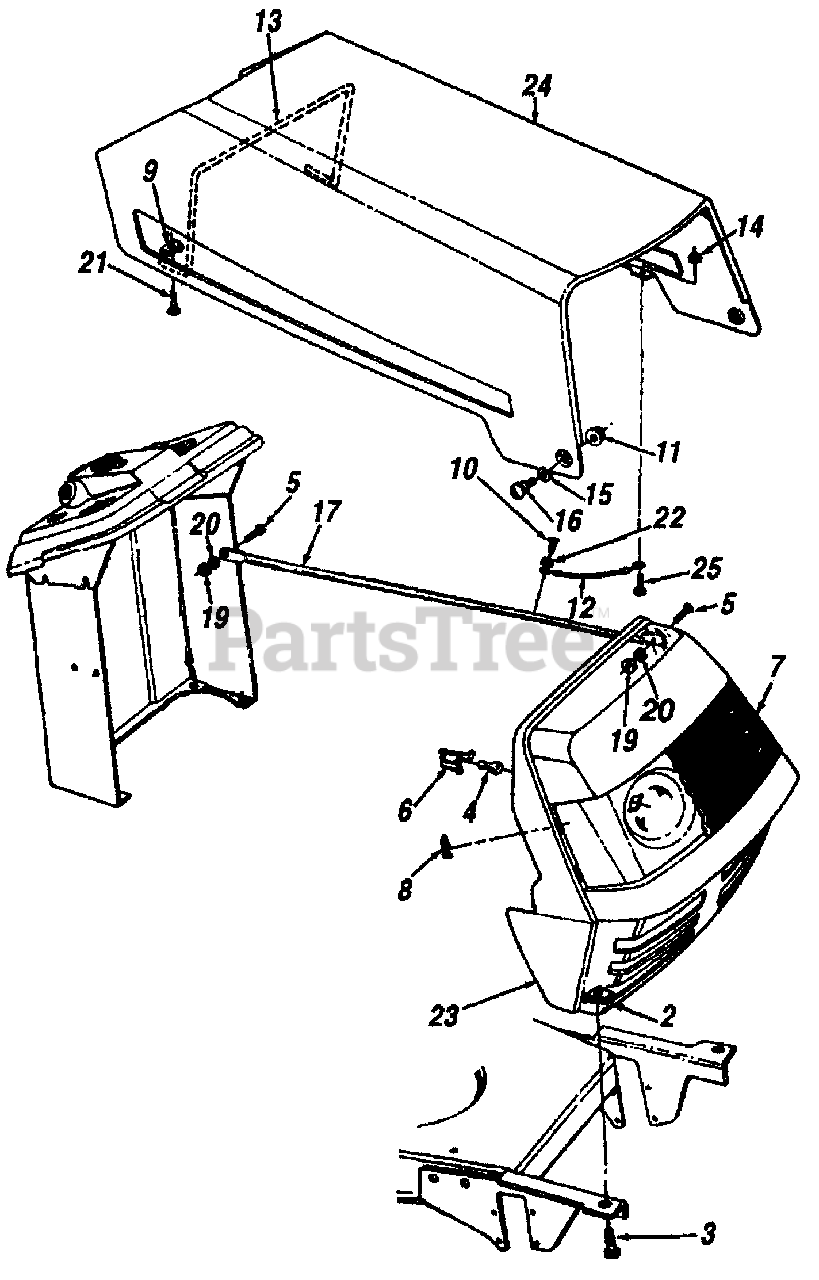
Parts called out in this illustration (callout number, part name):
2	U-Nut 5/16-18 Thd.
3	Hex Bolt 5/16-18 x .75" Lg.
4	Bulb
5	Hex Bolt 1/4-20 x .62" Lg.
6	Socket
7	Lens
8	Int. Cotter Pin 5/16" Dia.
9	Speed Nut
10	Truss Mach. B-Tap Scr. #10 x .5"
11	Lock Nut 1/4-20 Thd.
12	Hood Stop
13	Hood Spring
14	Hex Sems Nut #10-24 Thd.
15	Spring Washer .39" I.D. x .62" O.D.
16	Shld. Bolt
20	Lock Washer 1/4" I.D.
21	Hex Tap Scr. #10-16 x .75" Lg.
22	Fl-Washer .218" I.D. x .62"
